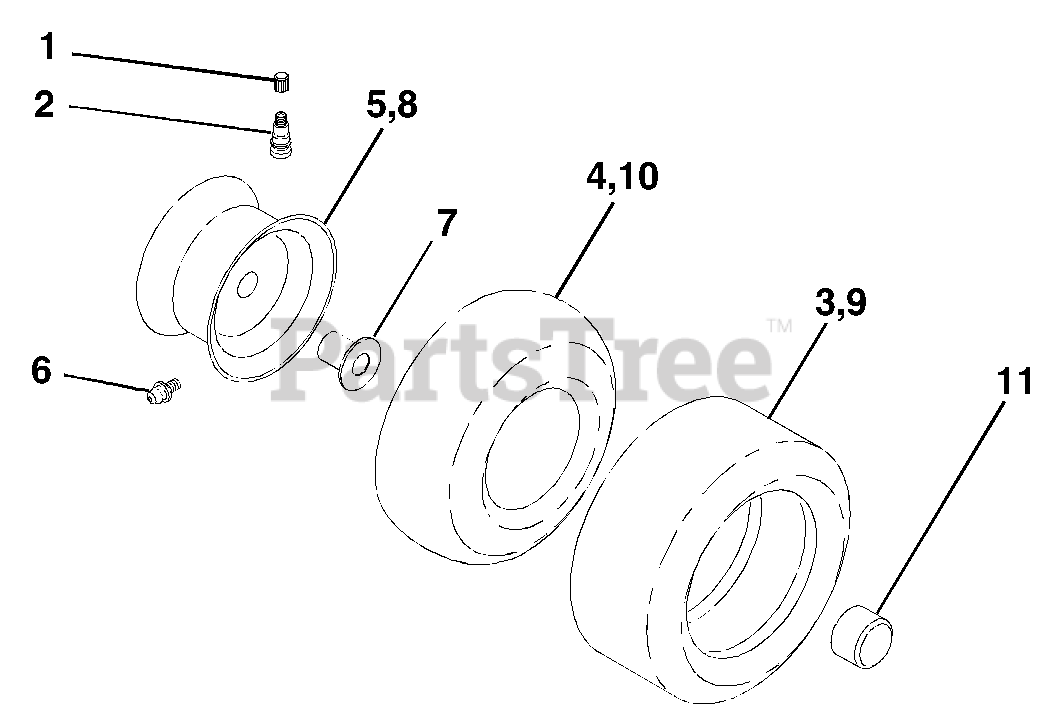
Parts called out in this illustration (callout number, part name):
1	Cap Valve Tire
2	Stem Valve
3	Tire F T 15 X 6 0 - 6 Service
4	Tube Front (Service Item Only)
5	Rim Asm 6" front Service
6	Fitting Grease (Front Wheel Only)
7	Bearing Flange (Front Wheel Only)
8	Rim Asm 8" rear Service
9	Tire R T 20x10-8 Service
10	Tube Rear (Service Item Only)
11	Cap Axle Blk 1 50 X 1 00
